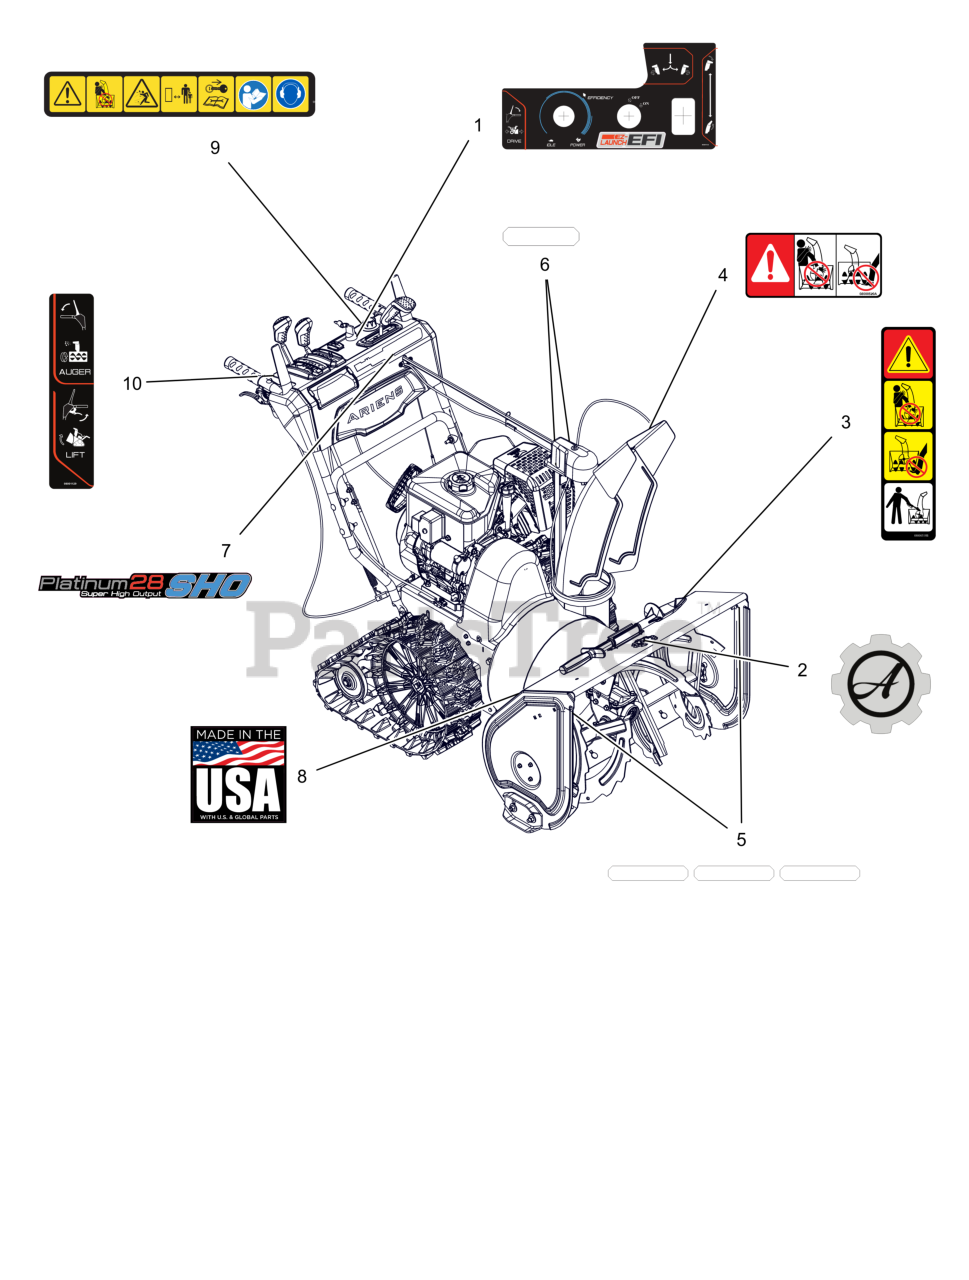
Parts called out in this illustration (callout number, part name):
1	DECAL, CONTROL - QT EFI W/GEL
2	DECAL, ARIENS - GEAR BADGE
3	DECAL, DANGER - ROTATING PARTS
4	DECAL, DANGER
5	DECAL,REFLECTIVE,HOUSING
6	DECAL,REFLECTIVE,GEAR COVER
7	DECAL, DASH, PLATINUM 28 SHO
8	DECAL, MADE IN USA
9	DECAL,DASH - SAFETY/EFI
10	DECAL,CONTROL-RH TRACK
